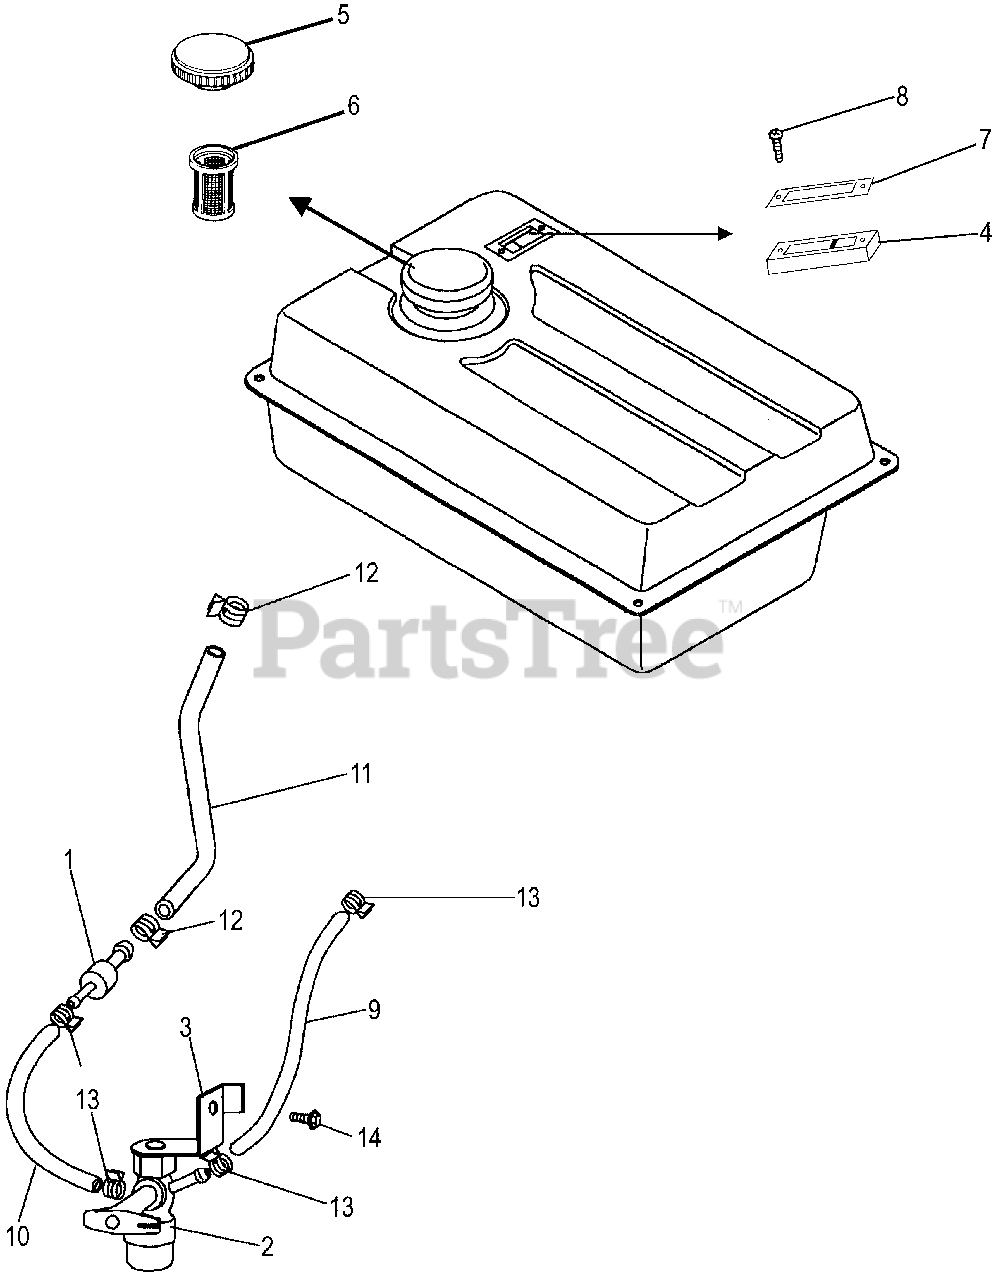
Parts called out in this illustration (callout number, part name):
1	FILTER, FUEL
2	PETCOCK ASSY.
3	STAY, PETCOCK
4	METER ASSY., FUEL
5	CAP, FUEL FILLER
6	FILTER, FUEL
7	MARK, FUEL METER
8	SCREW, FLAT (5X10)
9	BULK HOSE, FUEL (4.5X3000) (4.5X120)
10	BULK HOSE, FUEL (4.5X3000) (4.5X120)
11	BULK HOSE, FUEL (5.5X3000) (5.5X250)
12	CLIP, TUBE (10.5MM)
13	CLIP, TUBE (C9)
14	BOLT, FLANGE (6X12) Use up to Engine SN 1543277.
